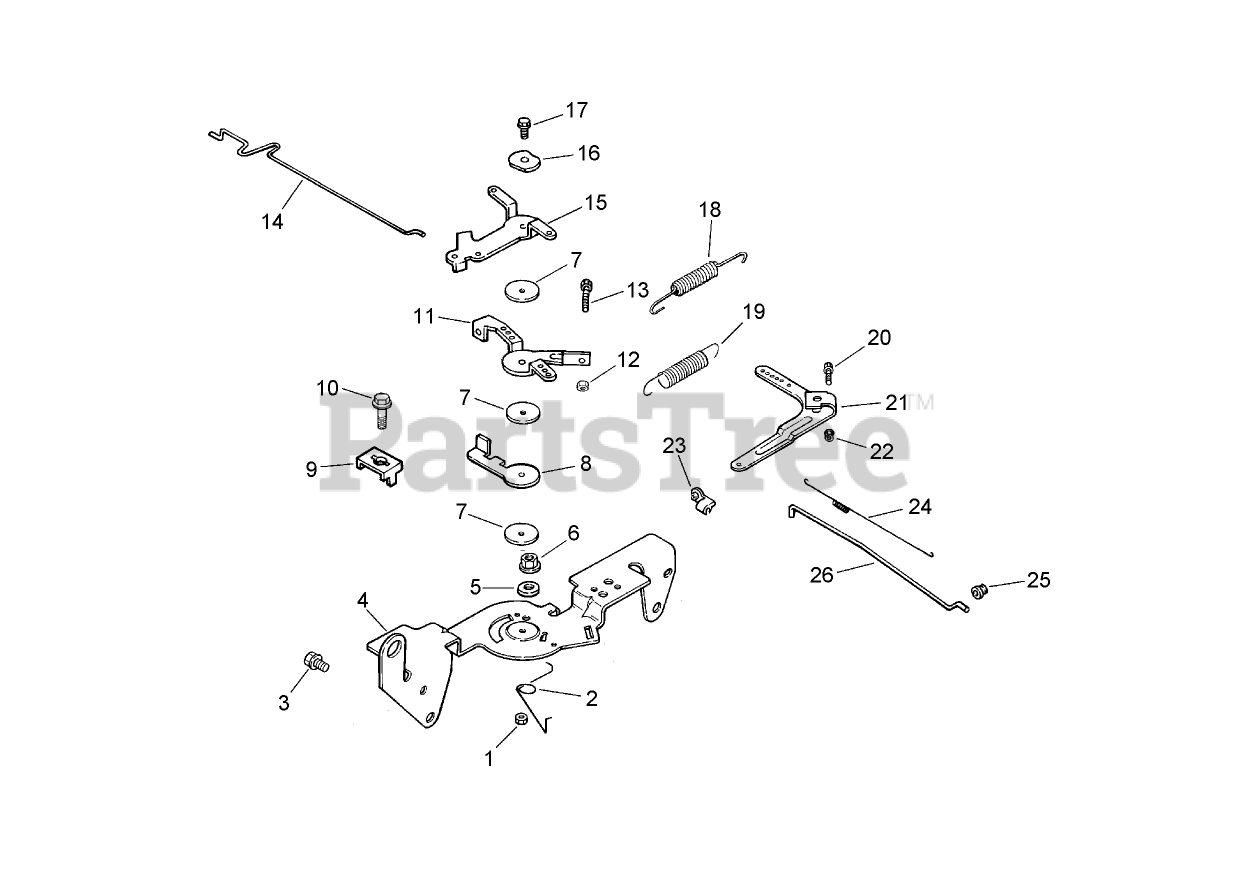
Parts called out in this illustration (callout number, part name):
1	NUT-LOCK (M5X.8)
2	SPRING-RETURN, CHOKE
3	SCREW-FLANGE, THREAD FORMING (M6X1.0X16)
4	Bracket-Control
5	Nut-HF (M5x0.8)
6	Washer-Lock (.25)
7	WASHER-FLAT (5.5MM)
8	Lever-Actuator, Throttle
9	CLAMP-CABLE
10	SCREW-FLANGE, THREAD FORMING (M5X0.8X16)
11	Lever-Control, Throttle
12	NUT (M4X0.7)
13	Screw (M4x0.7x30)
14	Linkage-Choke
15	LEVER-CHOKE
16	WASHER-SPRING (1/4)
17	SCREW-FLANGE, THREAD FORMING (M5X.8X20)
18	Spring-Limiter, Throttle
19	Spring-Governor (ORANGE)
20	BOLT-SQ NECK, RD HD (M6X1.0X25)
21	Lever-Governor
22	NUT-FLANGE (M6X1.0)
23	BUSHING-RETAINING, LINKAGE
24	SPRING-LINKAGE
25	BUSHING-LINKAGE, THROTTLE
26	Linkage-Throttle
